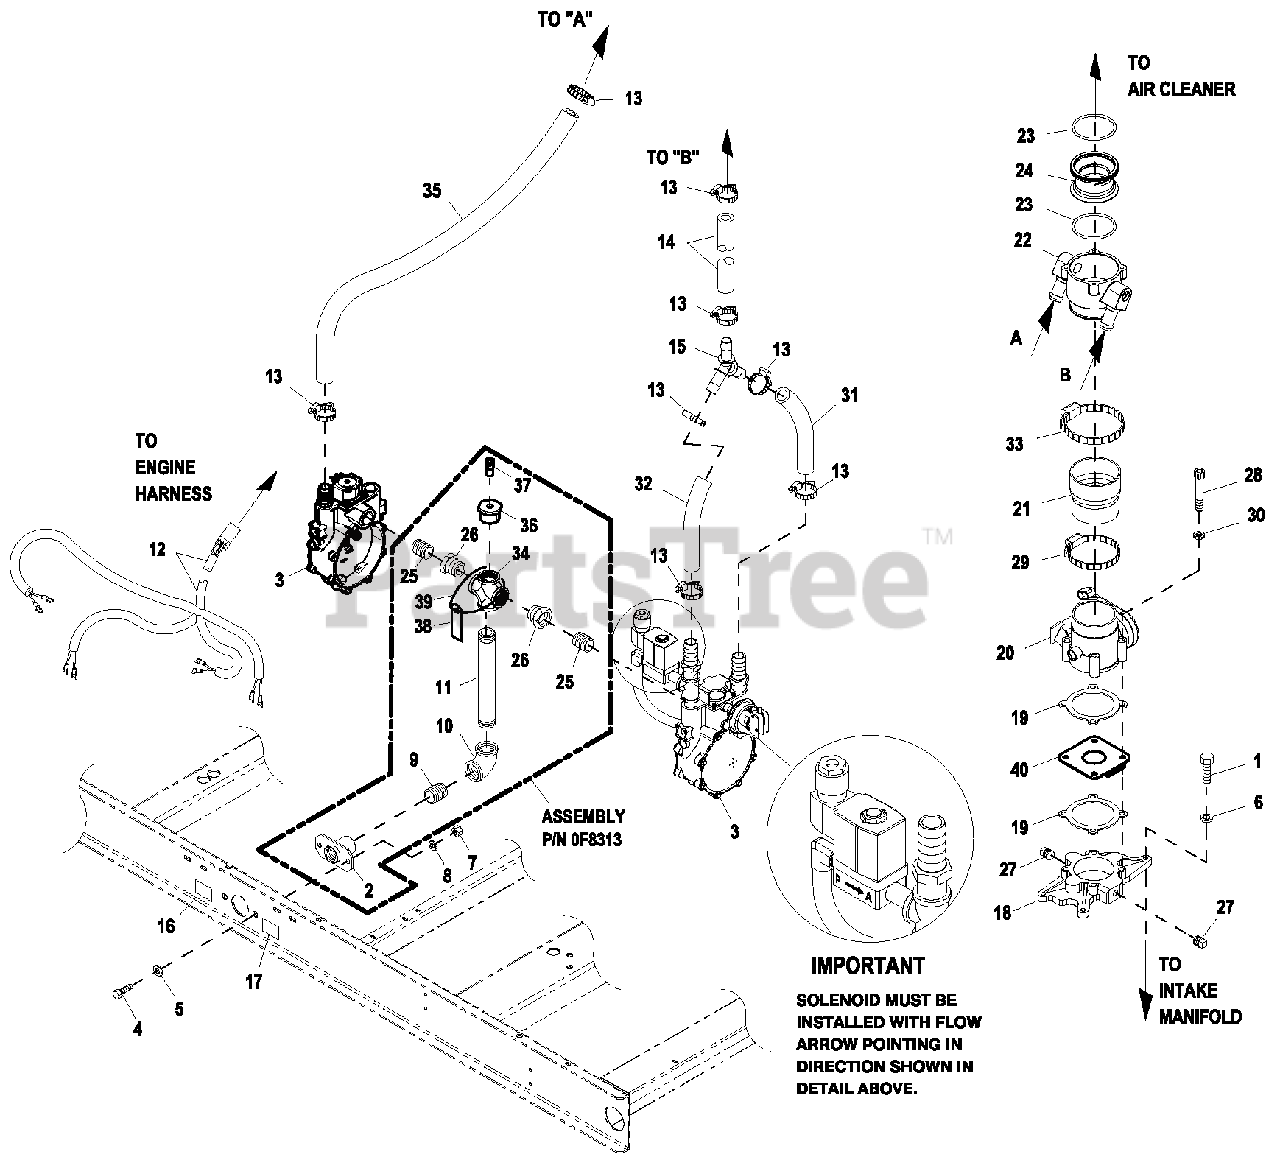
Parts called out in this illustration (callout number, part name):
1	SCREW HHC 5/16-18 X 1-1/4 G5
2	SUPPORT NAT GAS SOLENOID
3	REG ASSY 5 .4L 80KW NG CPL
4	SCREW HHC M12-1.75X20 G8 . 8
5	WASHER FLAT 1/2 ZINC
6	WASHER LOCK M8-5/16
7	NUTHEXM12-1. 75 G8 YELCHR
8	WASHER LOCK 1/2
9	NIPPLE CLOSE 1. 25 NPT X 1.625
10	ELBOW 90D 1-1/4 NPT
11	NIPPLE PIPE 1-1/4 NPT X 3 (100KW)
12	HARN FUEL JUMPER DUAL REG
13	CLAMP HOSE #8 . 53-1. 00
14	HOSE 3/4 ID SAE-30R2 (42" LG)
15	Y CONNECTOR 500 SERIES BARBS
16	DECAL INLET PRESSURE
17	DECAL FUEL INLET NG
18	MACHINING, INTAKE ADAPTOR 60MM
19	GASKET GOVERNOR ACTUATOR
20	ACTUATOR BOSCH 60 GOVERNOR
21	REDUCER 3 . 0" TO 2 . 75" TURBO
22	MIXER 40/60MM ACTUATOR ASSY
23	O-RING 2-3/4X3/32X2-15/16
24	VENTURI, THROTTLE 38MM
25	NIPPLE CLOSE 3/4X1. 375
26	BSHG RDCR HEX 1-1/4-3/4
27	PLUG STD PIPE 1/4 STEEL SQ HD
28	SCREW SHC M6-1.0X50 C8 . 8
29	CLAMP HOSE #44 2 .31-3 . 25
30	WASHER LOCK M6-1/4
31	HOSE 3/4 ID SAE-30R2 (12" LG)
32	HOSE 3/4 ID SAE-30R2 (9 . 5" LG)
33	CLAMP HOSE #52 2 .81-3 . 75
34	PIPE CROSS 1-1/4" NPT
35	HOSE 3/4 ID SAE-30R2 (45" LG)
36	BSHG RDCR HEX 1-1/4 X 1/4FNPT
37	PLUG, PRESSURE GAUGE, 1/4" NPT
38	HANG TAG FUEL PRESS TEST POINT
39	TIE WRAP UL 5 . 6 X . 10 BLACK
40	RESTRICTOR INTAKE 4 . 6L G3 NG
